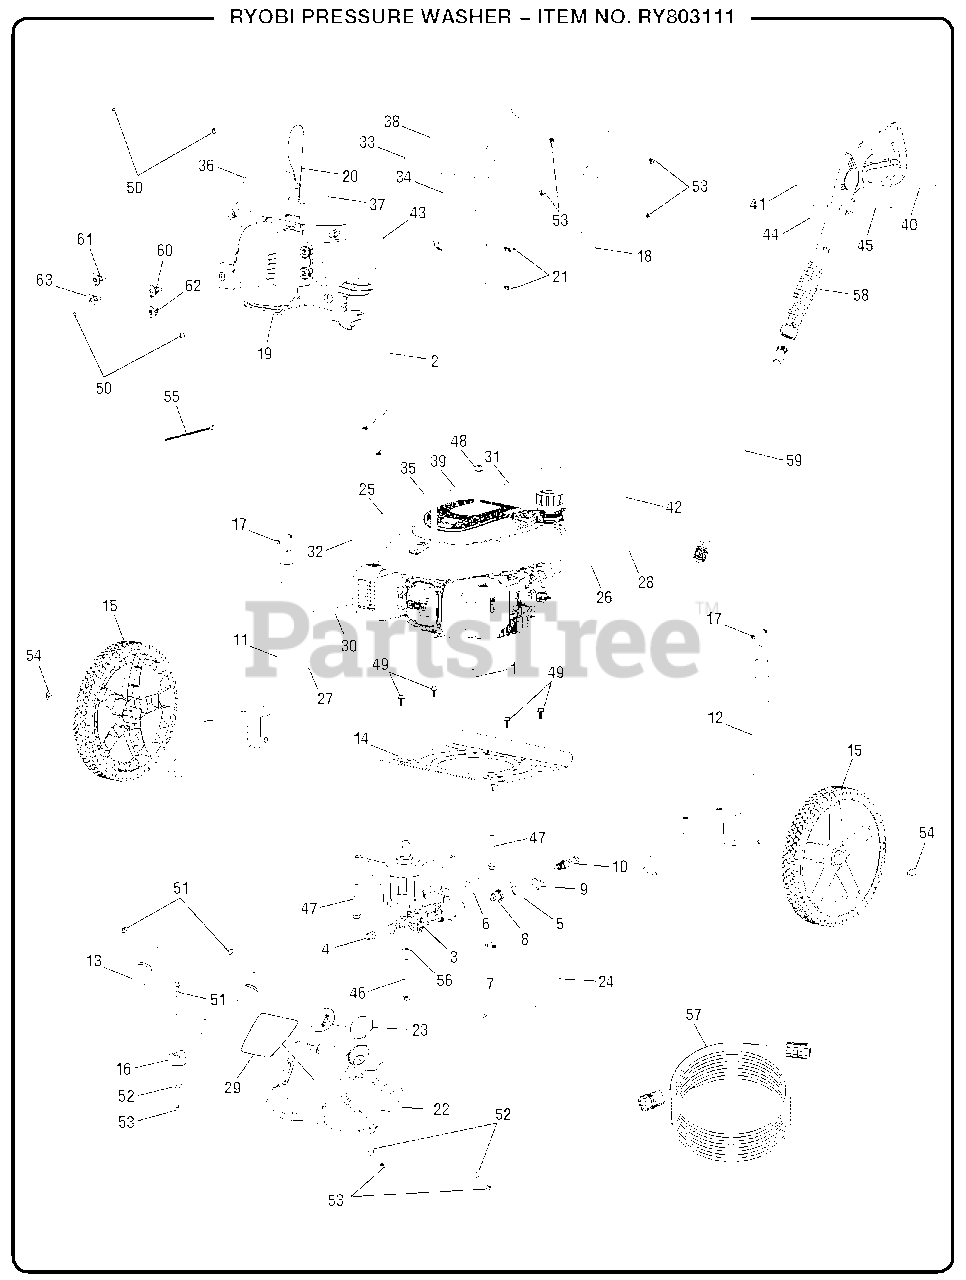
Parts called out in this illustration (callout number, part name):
1	Output Shaft Key
2	Wire Harness
3	Pump
4	Thermal Release Valve.
5	Inlet Filter Adapter
6	Outlet Tube
7	Soap Injector Kit
8	Inlet Filter Connector
9	Filter Screen
10	Unloader Valve Assembly
11	Frame Assembly
12	Frame Assembly
13	Frame Assembly
14	Engine Plate
15	Wheel
17	Spring Clip
18	Handle Assembly
19	Panel Assembly
20	Hose Holder Strap
22	Detergent Tank
23	Detergent Tank Cap
24	Detergent Injection Hose
25	Add Oil Label
26	Choke Label
27	Combustion Warning Label
28	Danger Label
29	Detergent Tank Label
30	Dipstick Hangtag
31	E85 Label
32	Hot Surface Label
33	Inquiries Label
34	Nozzle Hangtag
35	On/Off Label
36	Performance Label (PSI)
37	Performance Label (GPM)
38	Quick Start Hangtag
39	Shroud Label
40	Trigger Handle Warning Label (Fr/Sp)
41	Trigger Handle Logo Label
42	Danger Hangtag
43	Battery Connection Label
44	Trigger Handle Warning Label (Eng)
45	Trigger Handle Specification Label
46	Bolt (M8 x 65 mm, Hex Hd.)
47	Bolt (M8 x 45 mm, Flange Hd.)
48	Lock Nut (M8, Flange Hd.)
49	Bolt (M6 x 16 mm, Flange Hd.)
50	Bolt (M6 x 42 mm, T-30 Torx Pan Hd.)
51	Screw (M6 x 48 mm, T-30 Torx Hd.)
52	Washer (1/4 in.)
53	Lock Nut (M6)
54	Push Cap Nut
56	Washer (5/16 in.)
57	High Pressure Hose
58	Trigger Handle Assembly
59	Spray Wand
60	0deg Nozzle
61	25deg Nozzle
62	40deg Nozzle
63	Soap Nozzle
